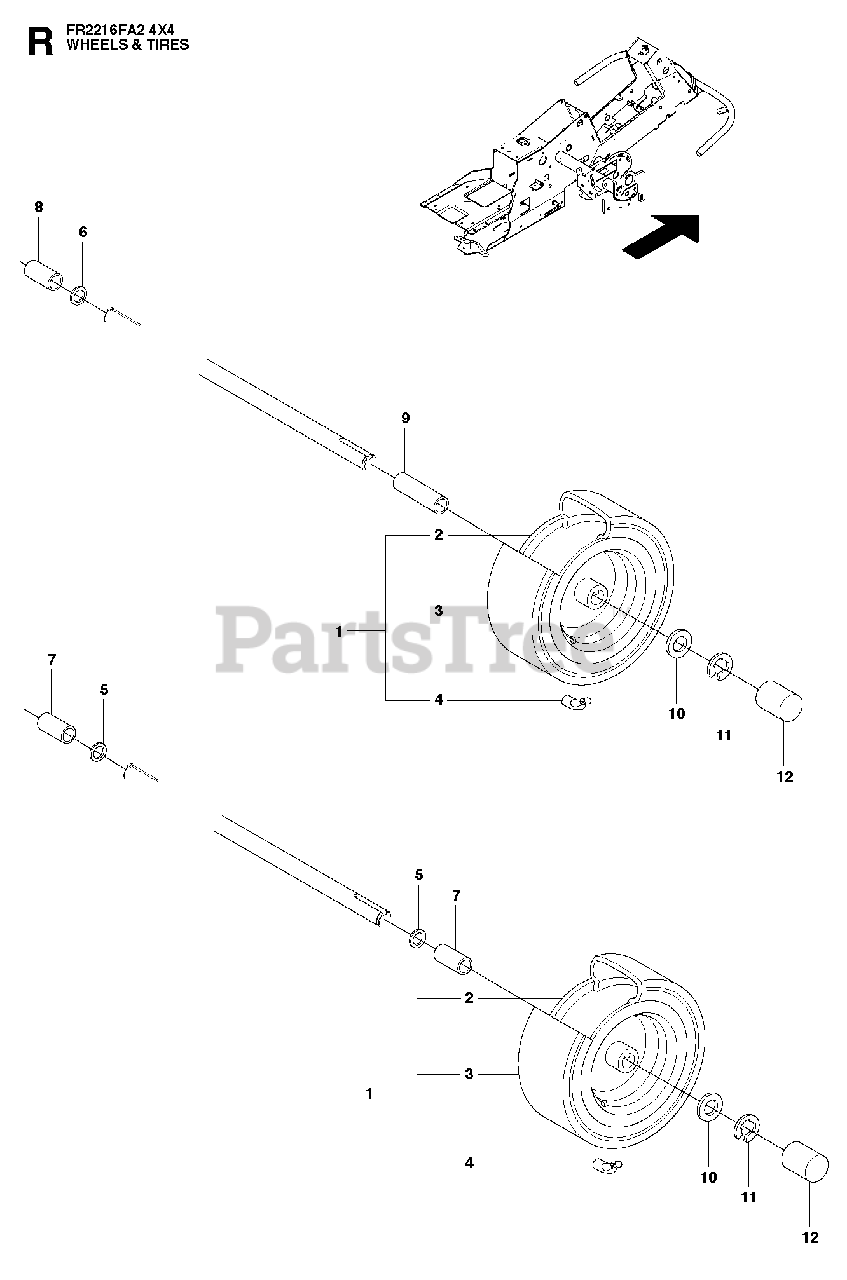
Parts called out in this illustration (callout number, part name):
2	RIM
7	SPACE SLEEVE
11	RETAINING RING
12	DUST CAP
